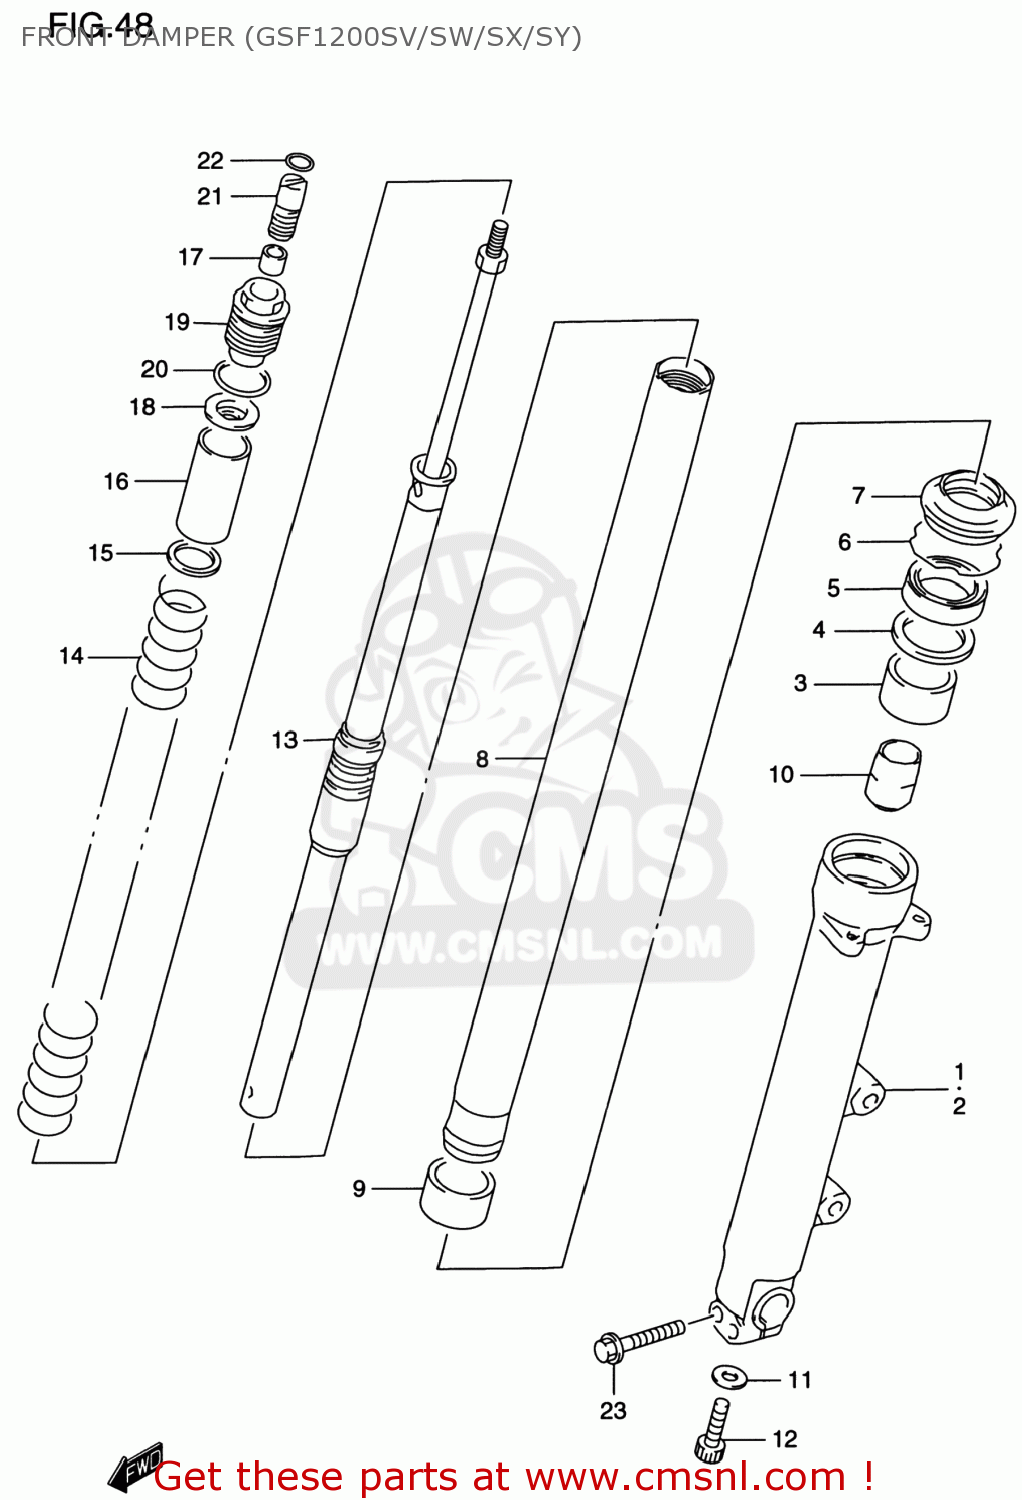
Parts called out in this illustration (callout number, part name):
1	TUBE,OUTER,R
2	TUBE,OUTER,L
3	BUSH,GUIDE
4	SPACER,SEAL
5	SEAL,OIL
6	CIRCLIP,FORK OIL SEAL
7	SEAL,DUST
8	TUBE,INNER
9	BUSH,SLIDE
10	PIECE,OIL LOCK
11	GASKET (NAS)
12	BOLT(8X27)
13	DAMPER,FRONT
14	SPRING,FR
15	SEAT,SPRING LWR
16	COLLAR,SPRING(35X37X50)
17	NUT
18	SEAT,SPRING UPR
19	BOLT,FORK
20	O RING
21	ADJUSTER,SPRING
22	O RING(D:2.5,ID:13.8)
23	BOLT
